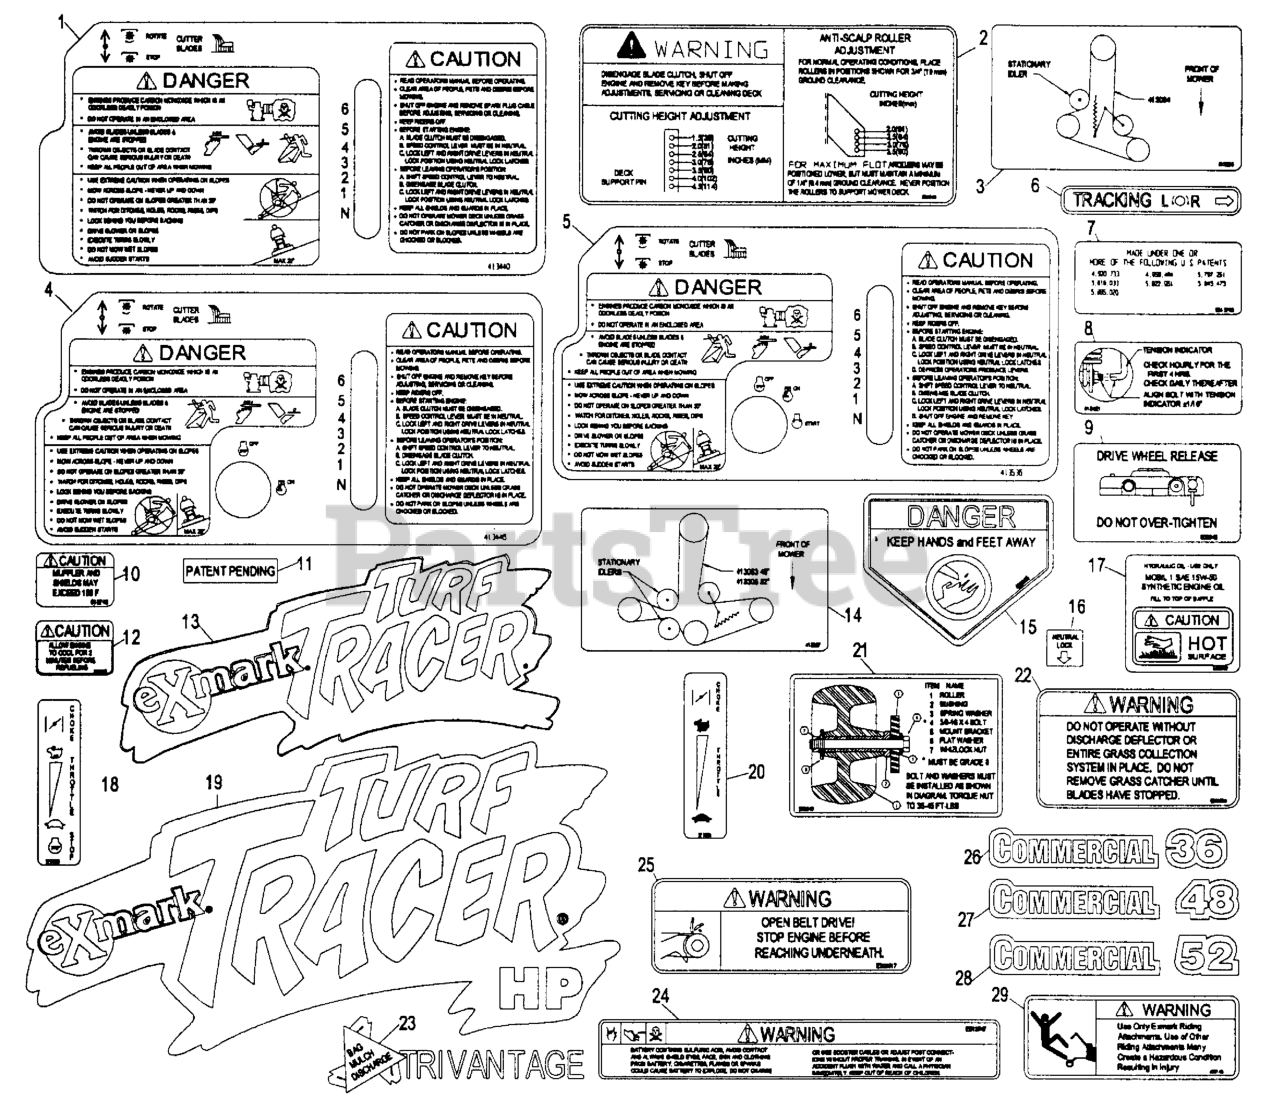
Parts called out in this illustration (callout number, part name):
2	DECAL,ANTI SCALP
3	DECAL,BELT ROUTING
6	DECAL,TRACKING ADJUST
8	DECAL,INDICATOR
9	DECAL,DRIVE RELEASE
11	Decal, Patent Pending
14	DECAL,BELT ROUTING
15	DECAL-DANGER
16	DECAL,NEUTRAL LOCK
20	DECAL,THROTTLE
21	DECAL,ROLLER MOUNTING
22	DECAL-WARNING, DISCHARGE
24	DECAL-BATTERY
25	DECAL,BELT DRIVE
26	DECAL,COMMERCIAL 36
27	DECAL,COMMERCIAL 48
28	DECAL,COMMERCIAL 52
29	DECAL,SULKY WARNING
